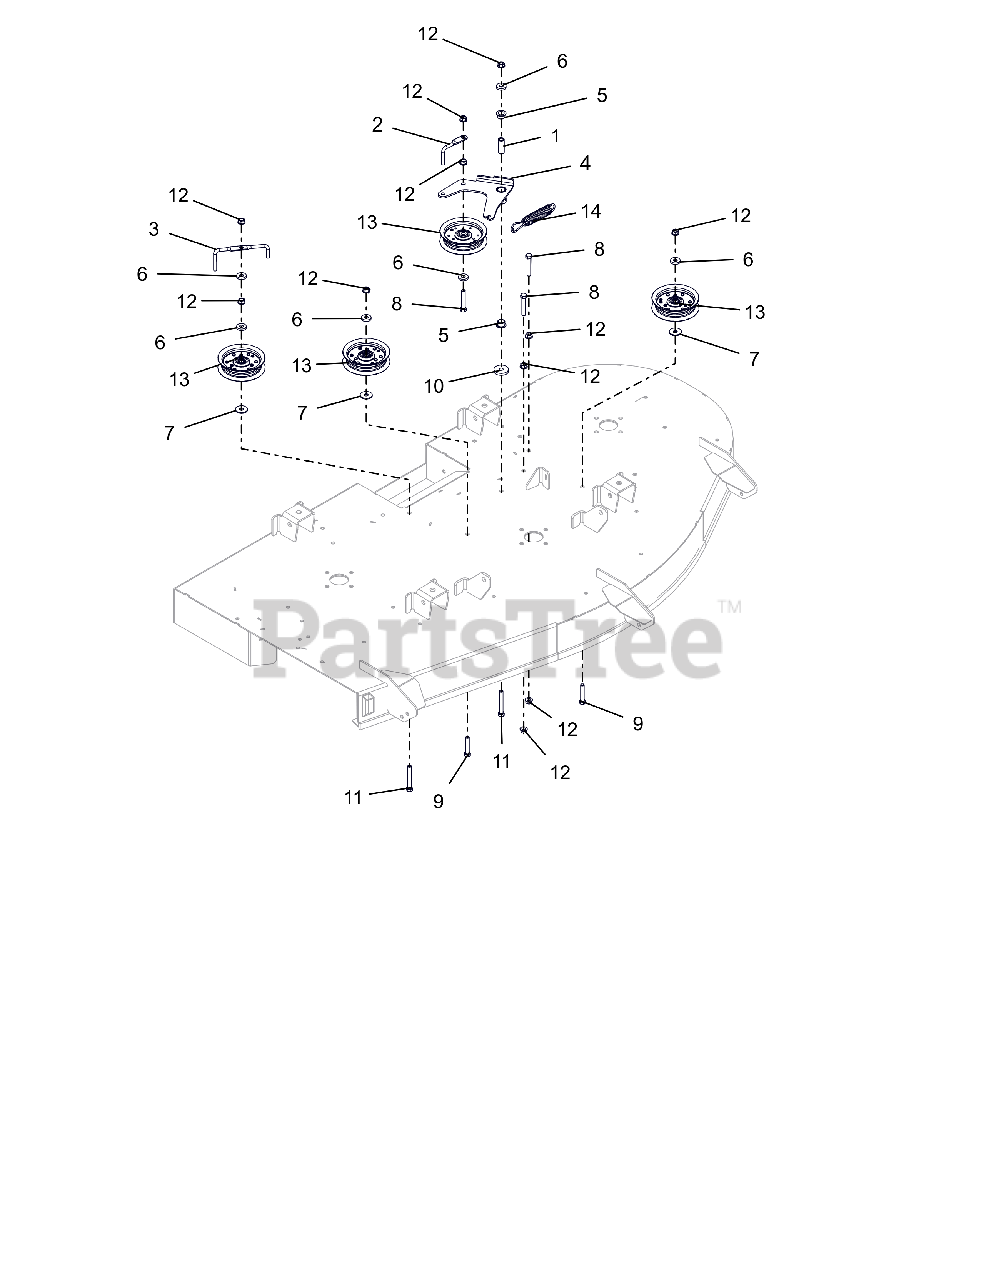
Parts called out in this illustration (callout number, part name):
1	SPACER, .375IDX.625ODX1.66 PM
2	WIREFORM, BELT FINGER
3	WIREFORM, BELT FINGER
4	WLDMT, IDLER ARM-42"
5	BSHG-FLG, .625X.750X.500X1.00
6	WSHR, FLT .406X1.00X.188 ZCC
7	WSHR FL STL .406X1.25X.10ZC120
8	BLT,HEX .38-16X2.25 G5 ZCC
9	BLT,HEX .38-16X2.00 G5 ZCC
10	WSHR, FLT .406X1.50X.245 ZCC
11	BLT, HEX .38-16X2.75 G5 ZCC
12	NUT-LK-TOP-FLG .38-16 ZC120
13	ASM, IDLER 4"
14	SG-TENS .135X.98X6.0 WLD 62
